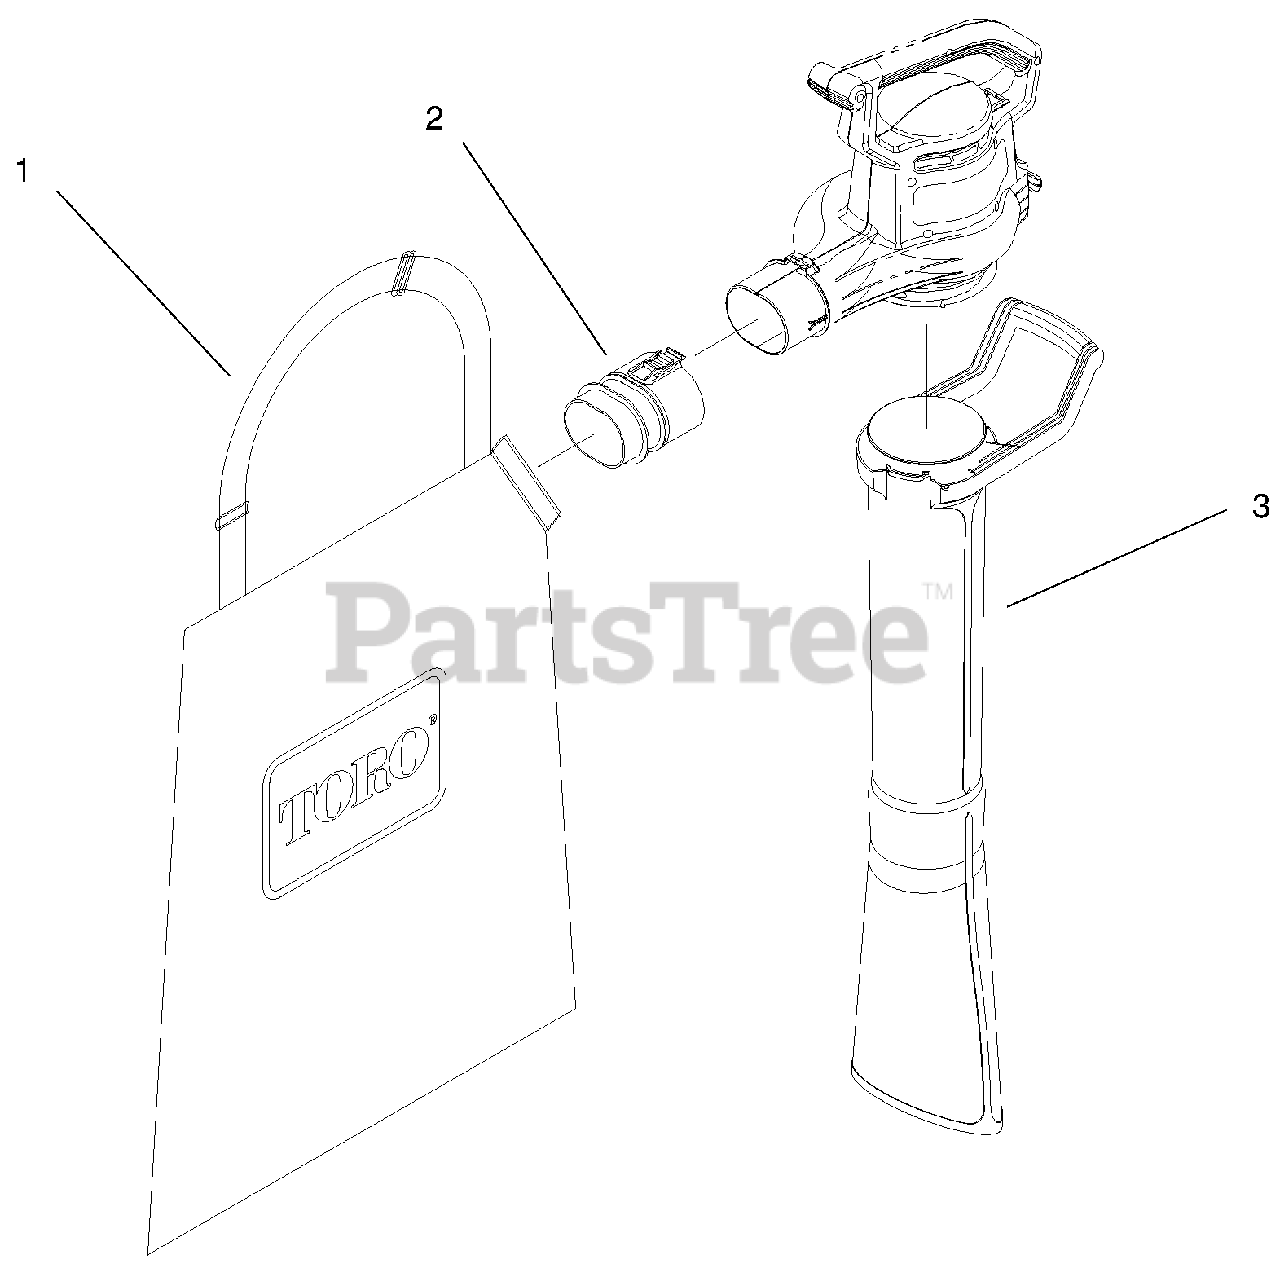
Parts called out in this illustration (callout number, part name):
1	Bag
2	Tube-Bag Inlet
3	Tube Asm
